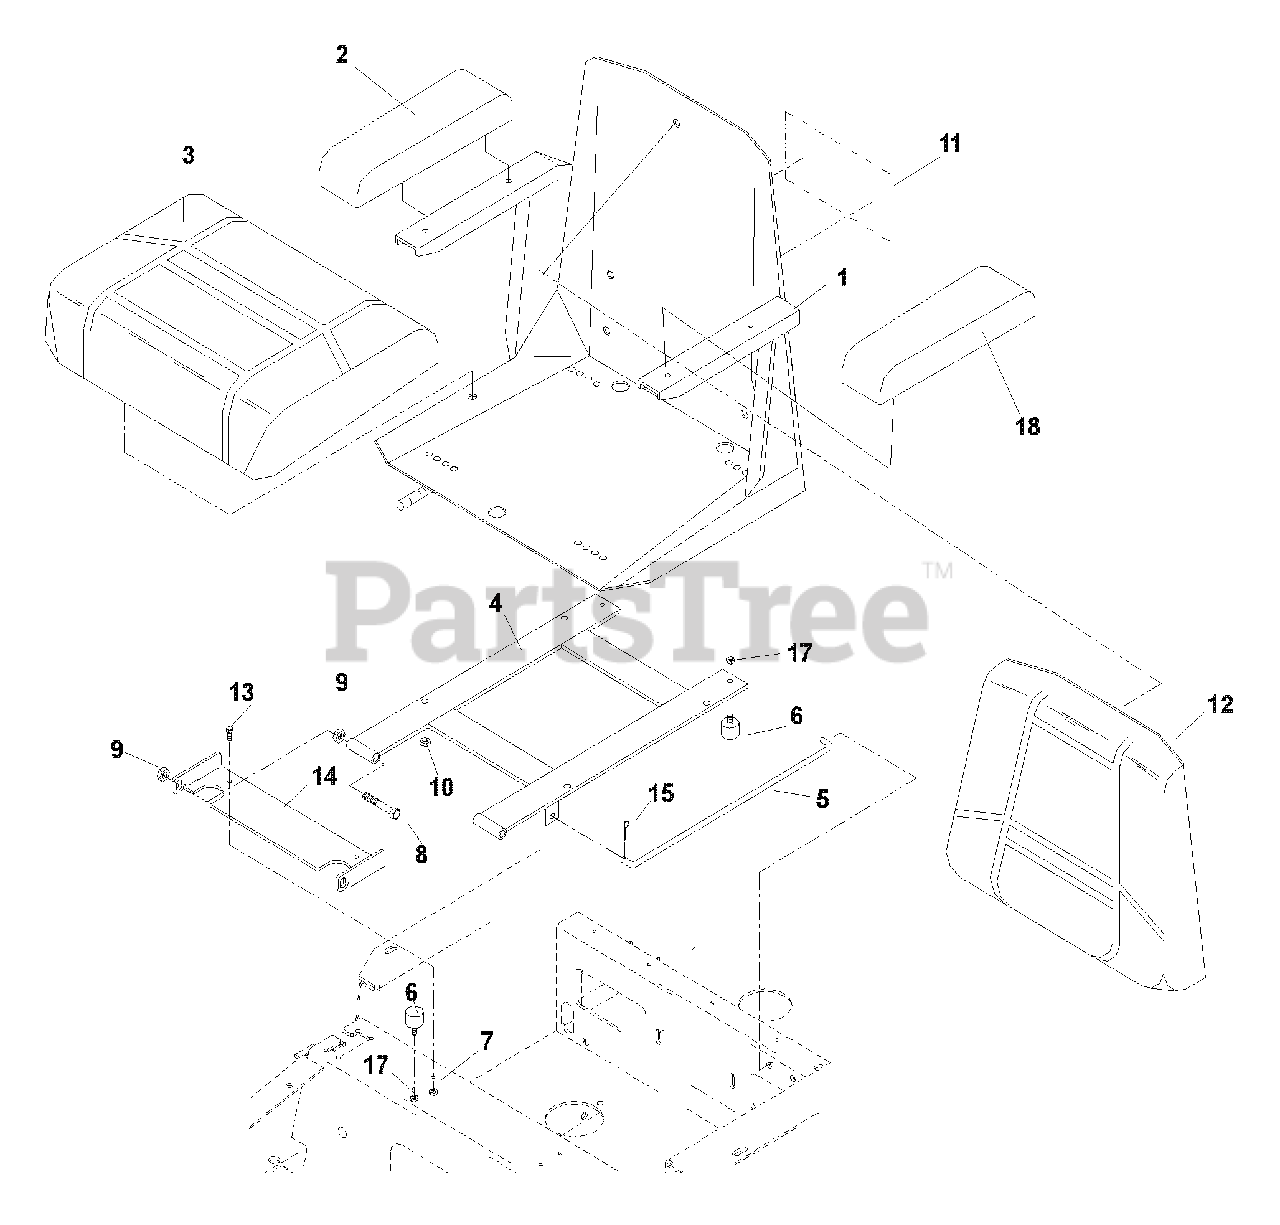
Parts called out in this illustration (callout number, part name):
1	SEAT, COMPLETE
2	ARM REST ASSEMBLY, RIGHT KIT
3	SEAT CUSHION KIT
4	SEAT MOUNT
6	STUD / PLATE MOUNT
7	1/4C LOCKNUT
8	HCS 3/8C X 3
9	NUT 3/8C CTR. LOCK
10	NUT 5/16C, NYLOC
11	DECAL, CROWN
12	SEAT BACK KIT
13	HCS 1/4C X 3/4
14	SEAT BKT. W/DECAL
15	COTTER PIN
17	NUT 1/4C NYLOC
18	ARM REST ASSEMBLY, LEFT KIT
